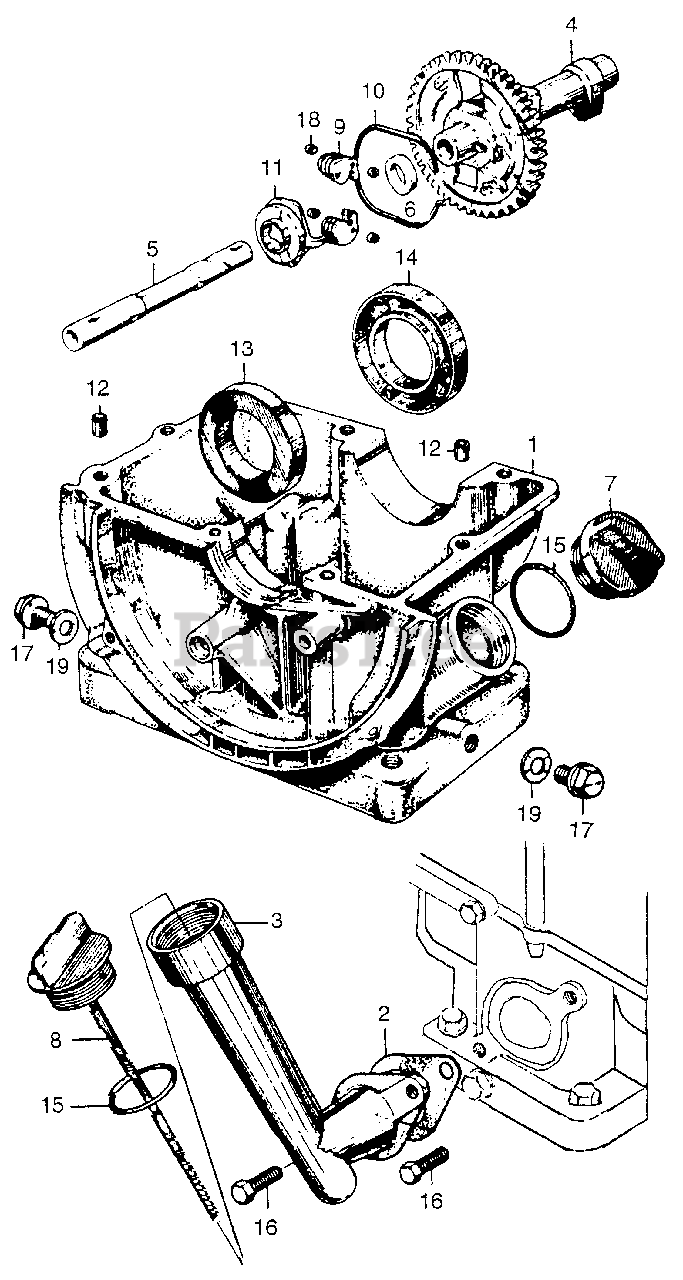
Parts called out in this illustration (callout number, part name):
2	GASKET, OIL PAN HOLE COVER (NOT AVAILABLE)
3	PIPE, OIL (NOT AVAILABLE)
4	CAMSHAFT (NOT AVAILABLE)
5	CENTER, CAMSHAFT (NOT AVAILABLE)
6	COLLAR, CAMSHAFT (NOT AVAILABLE)
7	CAP, OIL (YELLOW)
8	CAP, OIL (NOT AVAILABLE)
9	WEIGHT, GOVERNOR
10	CENTER, GOVERNOR WEIGHT (NOT AVAILABLE)
11	SLIDER, GOVERNOR (NOT AVAILABLE)
12	PIN, KNOCK (8.5X11) (NOT AVAILABLE)
13	OIL SEAL (PJ20528)
14	OIL SEAL (30X65X10) (NOT AVAILABLE)
15	O-RING (26X2.7)
16	BOLT, HEX. (6X16)
17	BOLT, DRAIN PLUG (12MM)
18	WASHER, PLAIN (3MM)
19	WASHER, DRAIN PLUG (12MM)
